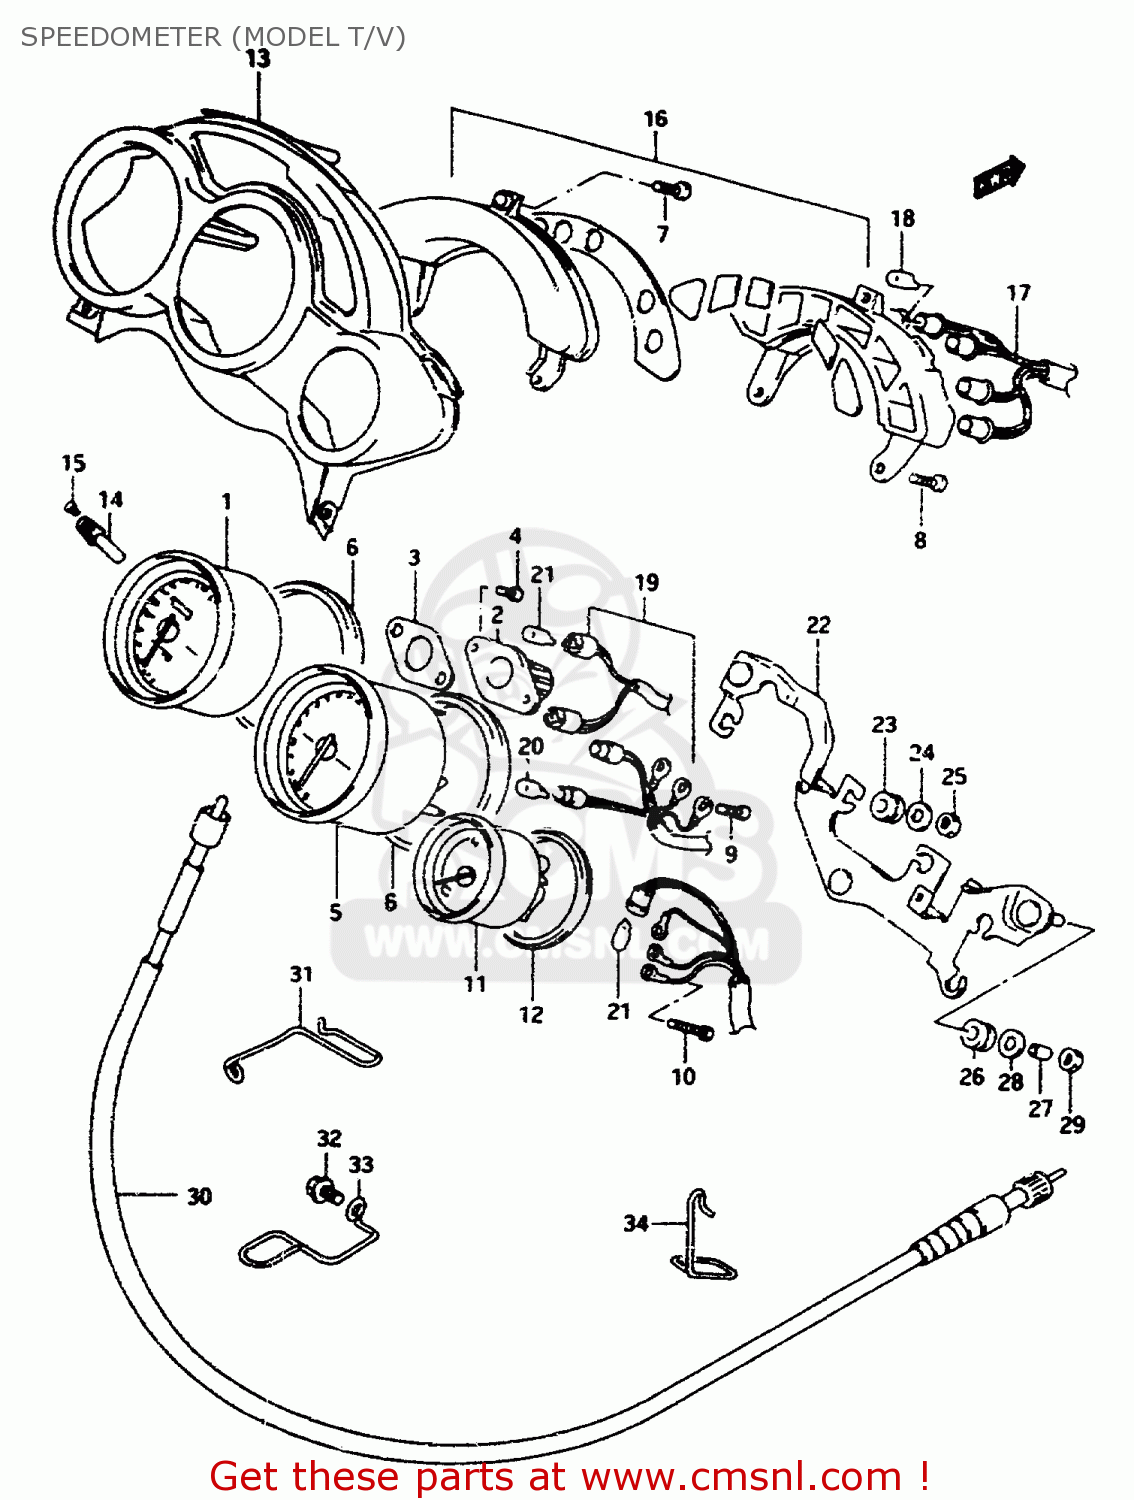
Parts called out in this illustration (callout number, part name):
1	SPEEDOMETER (KILO)
2	GEAR BOX
3	GASKET,METER GEAR BOX (NAS)
4	SCREW
5	TACHOMETER
6	CUSHION,METER
7	SCREW
8	SCREW
9	SCREW
10	SCREW(3X22)
11	METER,WATER TEMPERATURE
12	CUSHION,TEMP METER
13	VISOR
14	KNOB,TRIP METER
15	SCREW(2X6)
16	BOX ASSY,PILOT
17	CORD ASSY,PILOT BOX
18	BULB(12V3.4W,T10,BF175-01450A)
19	CORD ASSEMBLY
20	BULB(12V1.7W,WB372,T7)
21	BULB(12V1.7W,T6.5)
22	BRACKET,METER
23	CUSHION,METER
24	WASHER (4.3X13X0.80)
25	NUT
26	CUSHION
27	SPACER (6.1X8X9.5)
28	WASHER(6.5X18X1)
29	NUT
30	CABLE ASSY,SPEEDOMETER
31	GUIDE,SPEEDOMETER CABLE
32	BOLT
33	GUIDE,METER CABLE NO.2
34	GUIDE,SPEEDOMETER CABLE
